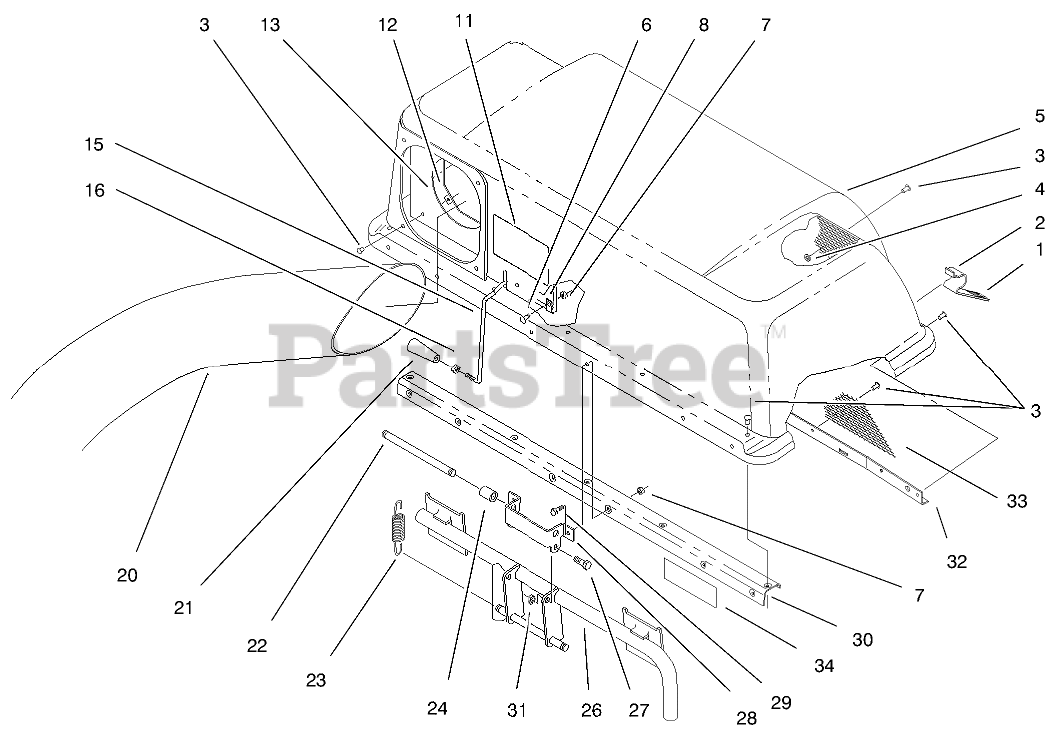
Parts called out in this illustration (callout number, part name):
2	Latch-Bag
3	RIVET-BLIND
4	WASHER-FLAT
5	TOP-BAGGER
6	SCREW-PPH
7	NUT-LOCK, NI
8	CLAMP
11	DECAL
12	CLAMP-SEAL
13	SEAL-CHUTE
15	FEELER-FILL, BAG
16	NUT-JAM
20	CHUTE-BAGGER
21	HANDLE-TAPERED
22	PIN-SPRING
23	SPRING-EXTENSION
24	Spacer
26	FRAME ASM
27	SCREW-HH
28	HINGE-BAG TOPB
29	SCREW-HH
30	Bagger-Stiffener
31	NUT-LOCK, NI
32	Screen Support
33	SCREEN-BAGGER
34	Decal-Caution
